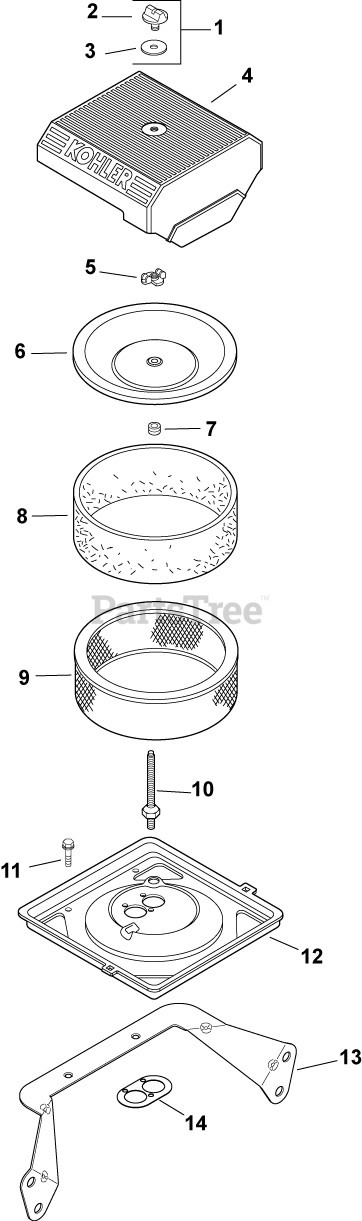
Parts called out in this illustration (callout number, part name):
1	KIT, KNOB W/SEAL
2	KNOB, COVER
4	COVER, AIR CLEANER
5	NUT, WING
6	COVER, INNER AIR CLEANER
7	SEAL, BREATHER
8	PRE-CLEANER (HIGH)
9	ELEMENT, AIR FILTER (HIGH) - Also available Retail Packaged 24 883 03-S1 Air Filter Kit
11	SCREW, FLG M6X1.0X12
12	BASE, AIR CLEANER-USE 24 094 83-S
13	BRACKET, AIR CLEANER BASE
14	GASKET, AIR CLEANER BASE
